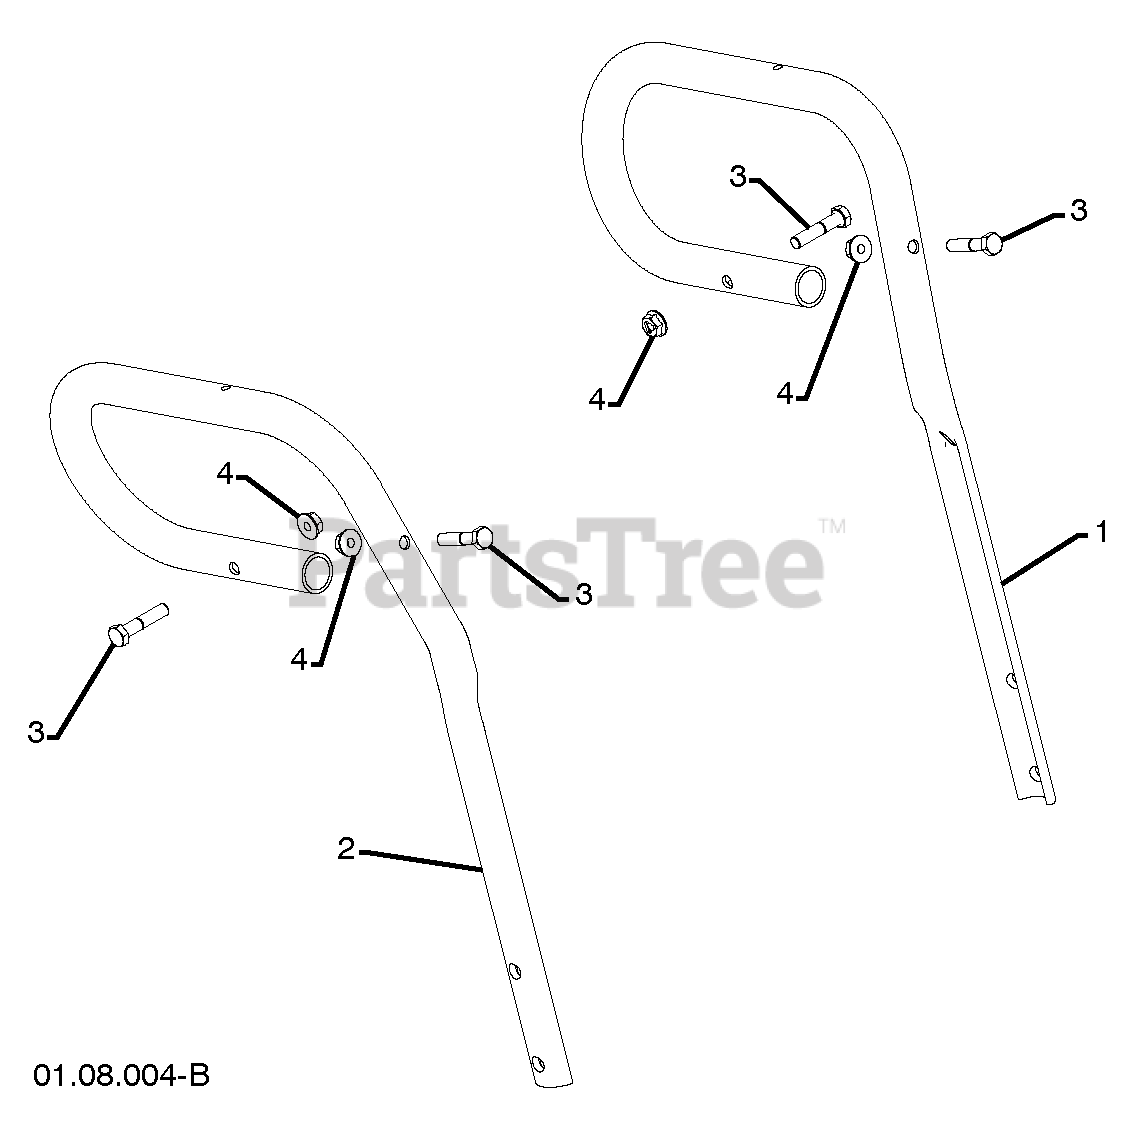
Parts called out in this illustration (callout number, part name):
1	LOOP HANDLE LH
2	LOOP HANDLE RH
3	SCREW 5/16-18 X 1.50
4	NUT 5/16-18
